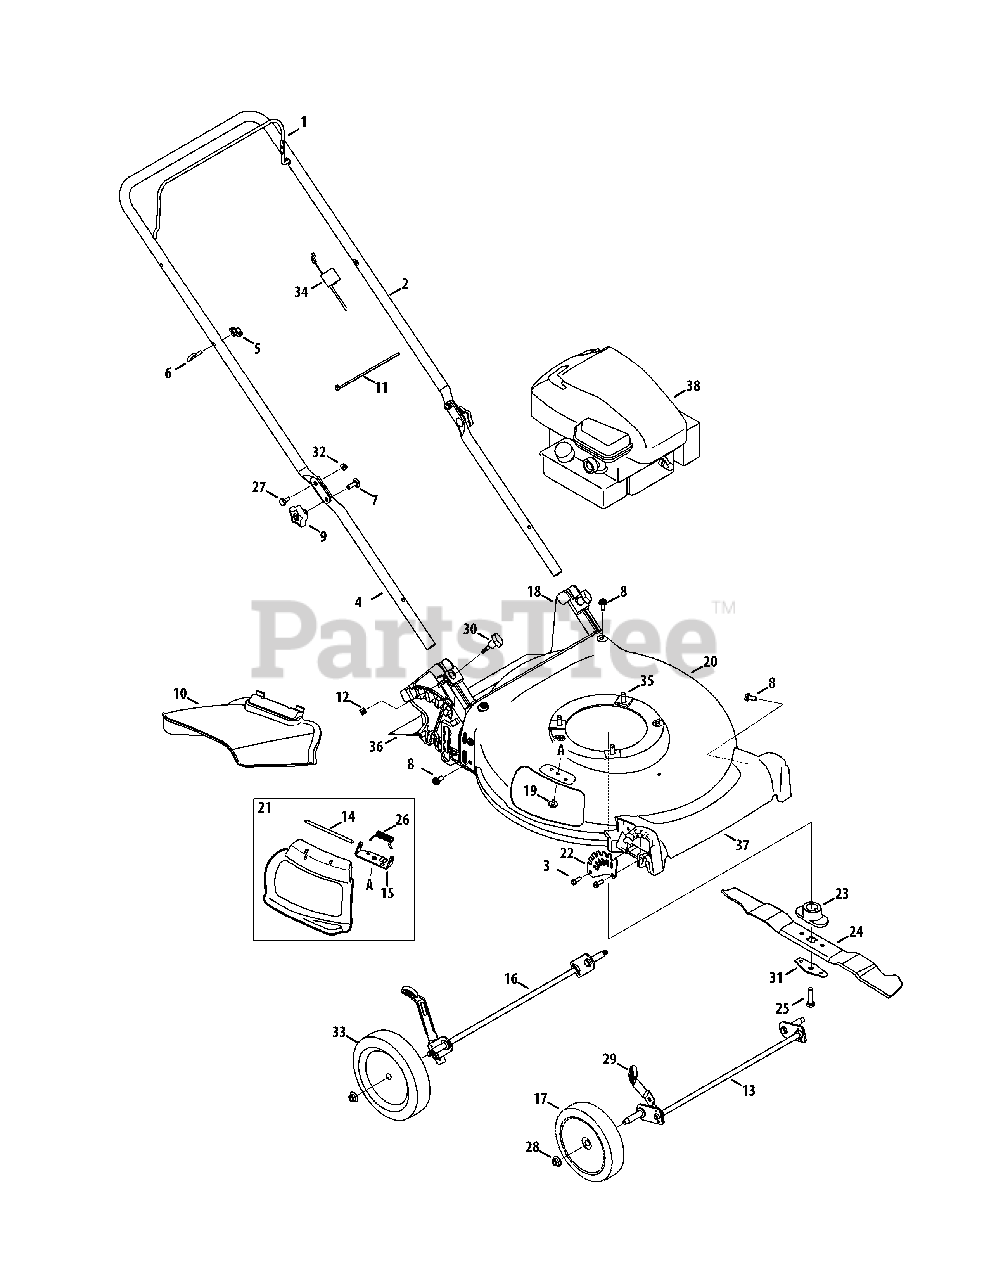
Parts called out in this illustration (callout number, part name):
1	Blade Control
2	Upper Handle
3	Screw, 1/4-15 x .750
4	Lower Handle
5	Wing Nut
6	Rope Guide
7	Carriage Screw ,5/16-18
8	Screw, 5/16-14 x .750
9	Hand Knob
10	Side Chute
11	Cable Tie
12	Nut, Sq., 1/4-20
13	Front Axle Assembly
14	Hinge Pin
15	Chute Deflector Bracket
16	Rear Axle Assembly
17	Wheel, 7 x 1.8
18	Rear Baffle
19	Screw, 1/4-20 x .500
20	Deck - 21"
21	Hinged Mulch Plug Assembly
22	Front Height Adjuster Plate
23	Blade Adapter
24	Mulching Blade
25	Screw , 3/8-24 x 1.50
26	Torsion Spring
27	Sldr. Screw, .375 x .126 x 1/4-20
28	Flange Lock Nut, 3/8-16
29	Adjustment Lever Knob
30	Wing Nut
31	Blade Bell Support
32	Nut, Flange Lock, 1/4-20
33	Wheel, 8 x 1.8
34	Control Cable
35	TT Sems Screw, 3/8-16 x 1.0
36	Trail shield
37	Front Cover
38	Engine - 10T802-3776-B1
